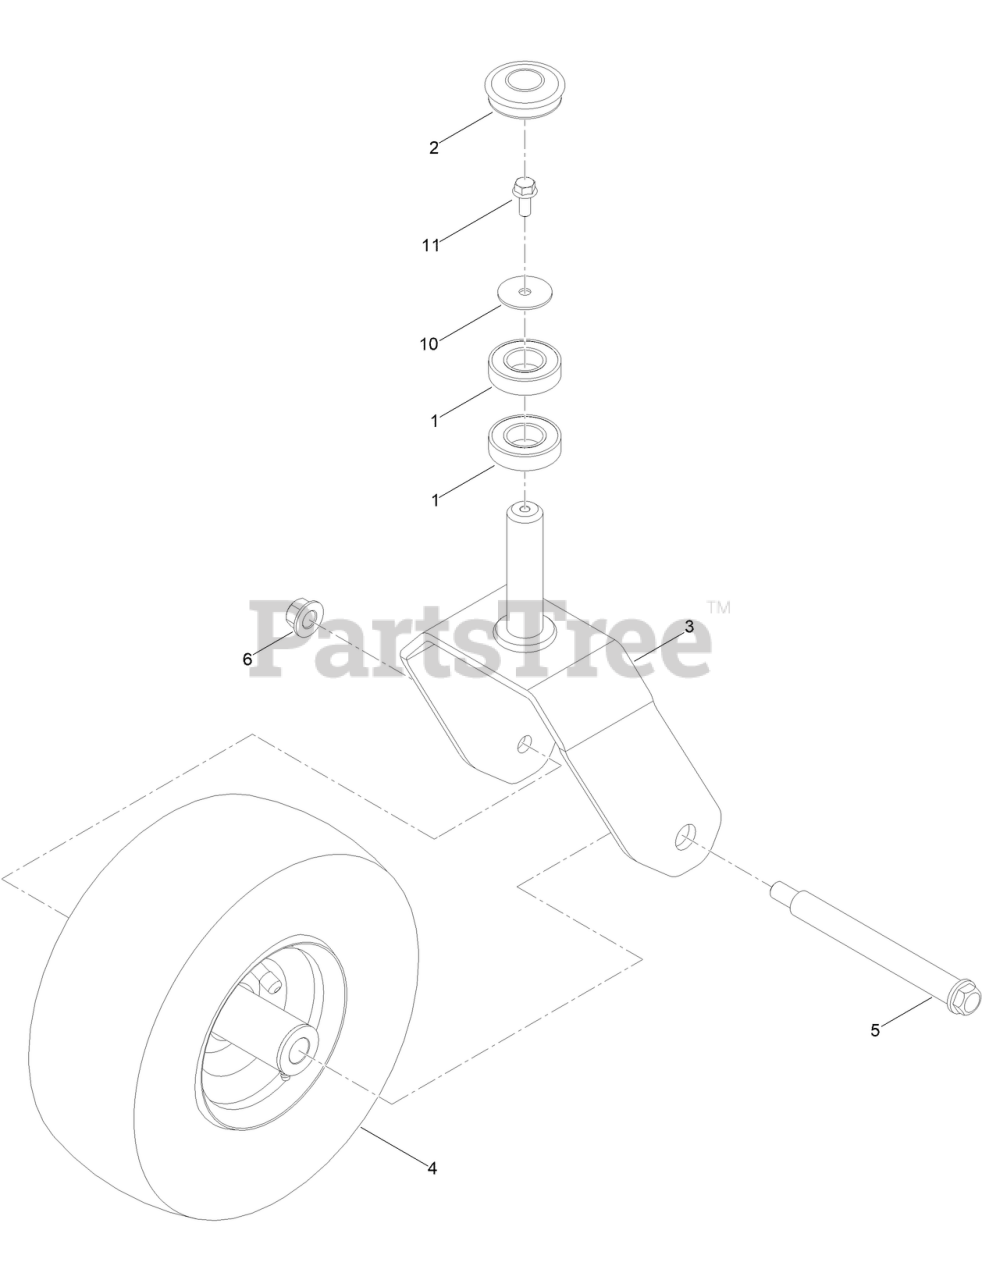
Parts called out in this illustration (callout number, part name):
1	BEARING-BALL
2	CAP,GREASE
4	WHEEL ASM - CASTER 12X6-5
5	SCREW-SHOULDER HHF
6	NUT-LOCK
10	WASHER-FLAT
11	SCREW-HHF
